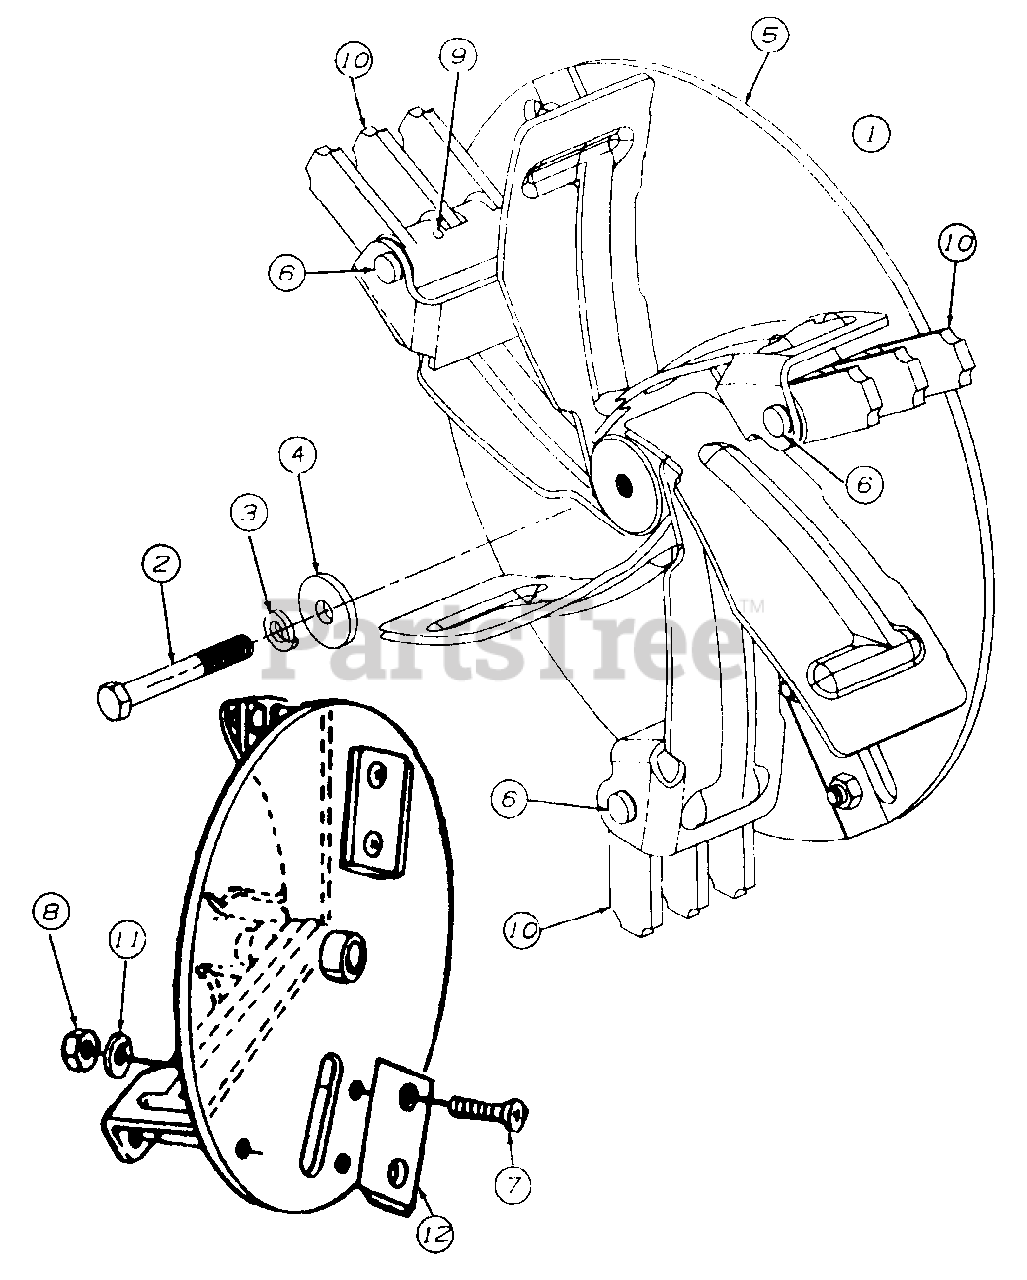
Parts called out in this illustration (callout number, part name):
1	IMPELLER ASSY COMP.
2	SCREW-HEX
3	WASHER-LOCK
4	WASHER-FLAT
5	IMPELLER ASSY
6	PIN-CLEVIS
7	SCREW-FLAT HEAD
8	NUT-HEX LOCK
9	PIN-ROLL SPRING
10	BLADE-FLAIL
11	WASHER-LOCK
12	BLADE-CHIPPER
